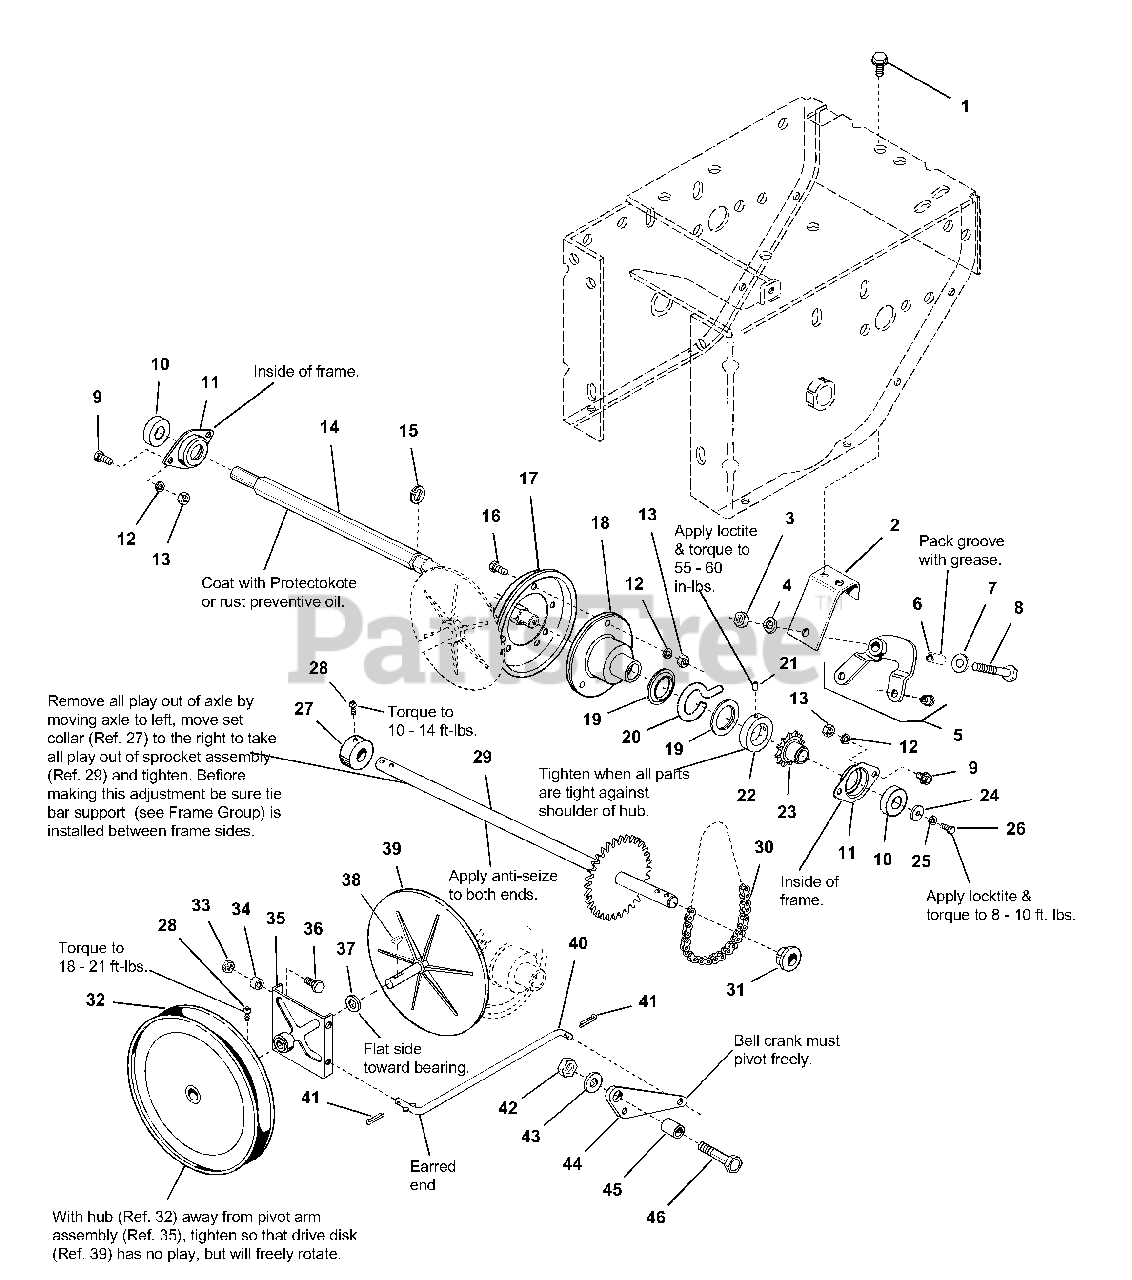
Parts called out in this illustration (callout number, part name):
1	SCREW, Taptite, 5/16-18 x 5/8
2	BRACKET
3	NUT, Hex, 3/8-16
4	LOCKWASHER, 3/8
5	SHIFT ARM ASSY, w/Bushing
6	BUSHING
7	WASHER
8	CAPSCREW, Hex Hd., 3/8-16 x 2
9	CAPSCREW, Hex Hd., 5/16-18 x 5/8
10	BEARING, Ball
11	RETAINER, Bearing
12	LOCKWASHER, 5/16
13	NUT, Hex 5/16-18
15	E-RING, Retaining
16	CAPSCREW, Hex. Hd. 5/16-18 x 3/4
17	DISC,Friction
18	HUB, Friction Disc
19	COLLAR, Thrust
21	SET SCREW, Hex Skt. Cup Pt.1/4-20 x 3/8
22	COLLAR, Set
23	SPROCKET, 10T
24	WASHER, Flat,
25	LOCKWASHER, 1/4
26	CAPSCREW, Hex Hd., 1/4-20 x 3/4
27	COLLAR, Set
28	SET SCREW,Sq. Hd., Cup Pt. 5/16-18 x 1/2
29	* AXLE & SPROCKET ASSY.
30	CHAIN, Roller, #40 x 25
32	PULLEY, Traction
33	NUT, Centerlock, Hex Flange Hd., 5/16-18
35	PIVOT ASSY.
36	CAPSCREW, Hex Hd. 5/16-18 x 5/8
37	WASHER
39	DRIVE, Disc,w/Spindle
41	PIN, Cotter 1/8 x 3/4
42	NUT, Hex Lock, Esna, 5/16-18
43	WASHER, Flat
44	BELLCRANK
45	BUSHING
46	CAPSCREW, Hex Hd. 5/16-18 x 1-3/4
